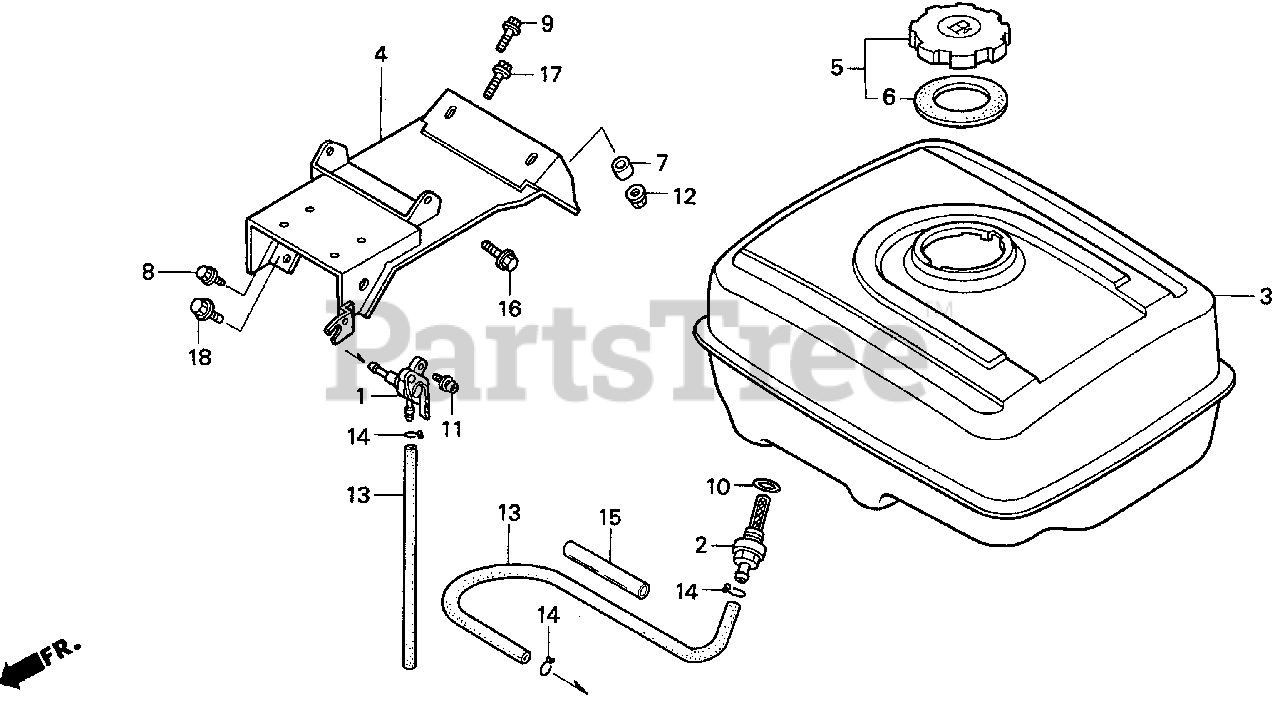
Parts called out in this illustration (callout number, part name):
1	PETCOCK ASSY.
2	JOINT, FUEL TANK
3	TANK, FUEL *NH1* (BLACK)
3	TANK, FUEL *R8* (BRIGHT RED)
4	STAY, FUEL TANK
5	CAP, FUEL FILLER
6	GASKET, FUEL FILLER CAP
7	COLLAR, FR. ENGINE HANGER (A)
8	BOLT, FLANGE (6X23)
9	BOLT, FLANGE (6X20) (CT200)
10	O-RING (13.5X1.5) (ARAI)
11	SCREW-WASHER (5X14)
12	NUT, FLANGE (8MM)
13	BULK HOSE, FUEL (4.5X3000) (4.5X260)
14	CLIP, TUBE (B8)
15	BULK HOSE, VINYL (9X11X3000) (9X11X180)
16	BOLT, FLANGE (8X16)
17	BOLT, FLANGE (8X25)
18	BOLT, FLANGE (8X30)
